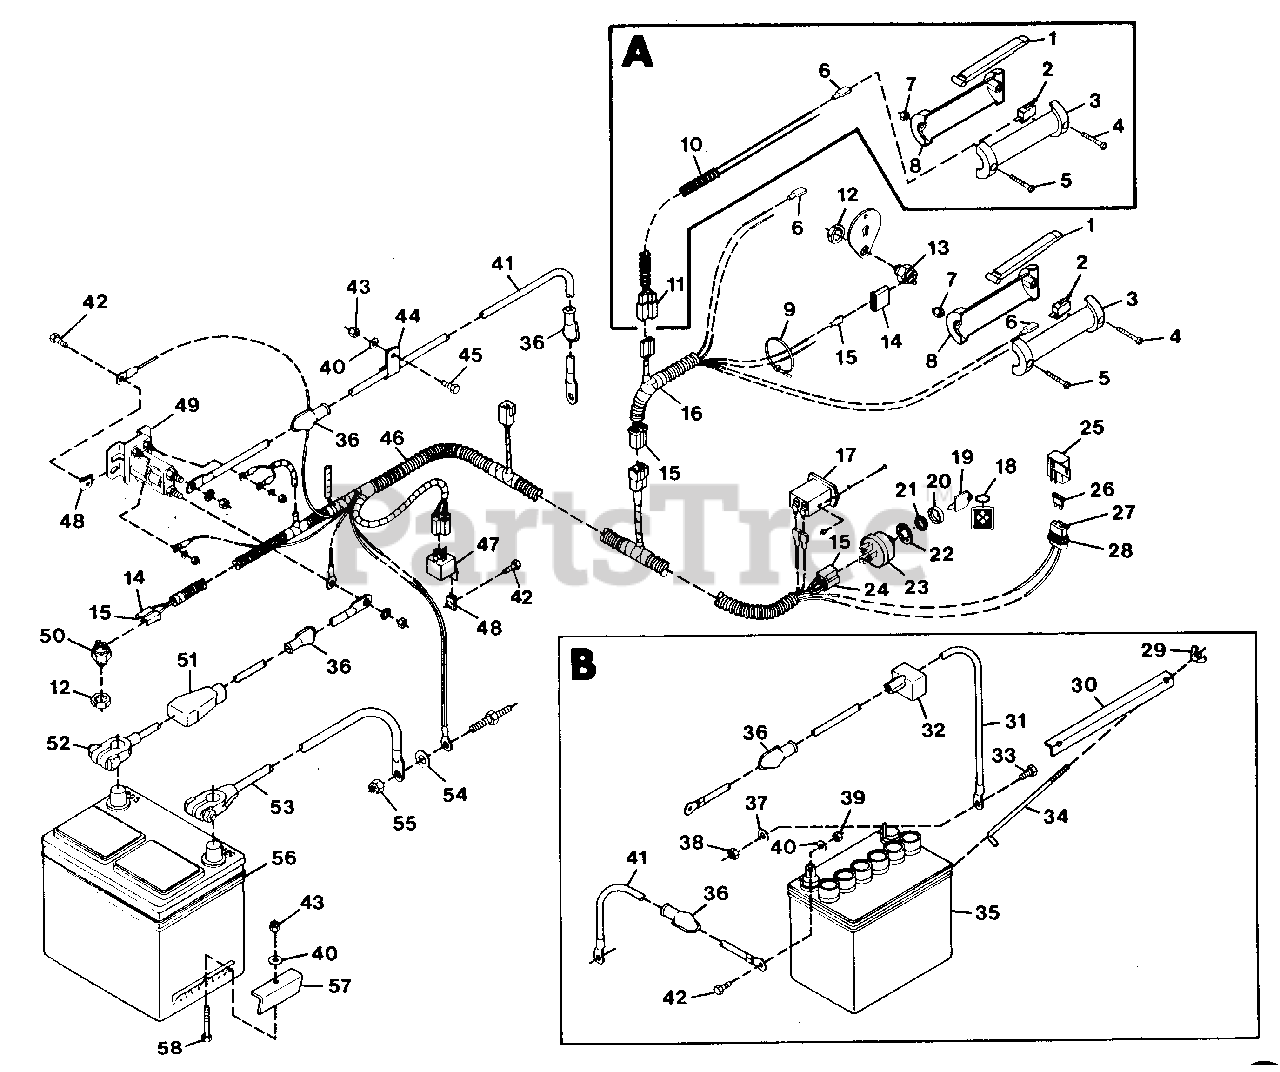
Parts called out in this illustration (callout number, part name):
1	LEVER
2	SWITCH
3	HANDLE, L.H.
4	SCREW, MACH. 10-24X.75 PHD
5	SCREW, MACH. 10-24X1.50 PHDCR
6	TERMINAL, FEMALE
7	NUT, LOCK 10-24
8	HANDLE, R.H.
9	TIE WRAP, BLACK
10	HARNESS, STEERING BRAKE
11	CONNECTOR
12	NUT, STAMPED 9/16-18
13	SWITCH, NEUTRAL START
14	EYELET TERMINAL
15	TERMINAL
16	HARNESS, WIRING HANDLEBAR
17	HOURMETER
18	CHAIN, KEY
19	KEY, IGNITION SWITCH
20	BOOT, FOR 9/16 SWITCH
21	NUT, 9/16-24 FOR SWITCH
22	WASHER, LOCK
23	SWITCH, IGNITION
24	CONNECTOR
25	COVER
26	FUSE, 25 AMP
27	TERMINAL, FOR 10-12 GA. WIRE
28	CONNECTOR
29	NUT, WING 1/4-20
30	HOLD DOWN, BATTERY
31	CABLE, BATTERY TO SOLENOID
32	BOOT, BATTERY CABLE
33	BOLT, HEX 5/16-18X.625
34	HOOK, BATTERY HOLD DOWN
35	BATTERY, 12 VOLT
36	BOOT, BATTERY CABLE
37	WASHER, FLAT .344X.688X.065
38	NUT, HEX 5/16-18
39	NUT, HEX 1/4-20
40	WASHER, FLAT .281X.625X.065
41	CABLE, SWITCH TO STARTER
41	CABLE, NEGATIVE BATTERY
42	BOLT, HEX 1/4-20X.625
43	NUT, LOCK 1/4-20
44	CLAMP, NYLON
45	BOLT, HEX 1/4-20X.75
46	HARNESS, WIRING
47	RELAY
48	NUT, SPEED 1/4-20
49	SWITCH, MAGNETIC
50	SWITCH, INTERLOCK
51	COVER, BATTERY TERMINAL
52	CABLE, POSITIVE BATTERY
53	CABLE, NEGATIVE BATTERY
54	WASHER, FLAT .469X.938X.065
55	NUT, LOCK 3/8-16
56	BATTERY, 12 BOLT
57	CLAMP
58	BOLT, HEX 1/4-20X2.00
NS	DECAL, E.S. WARNING
